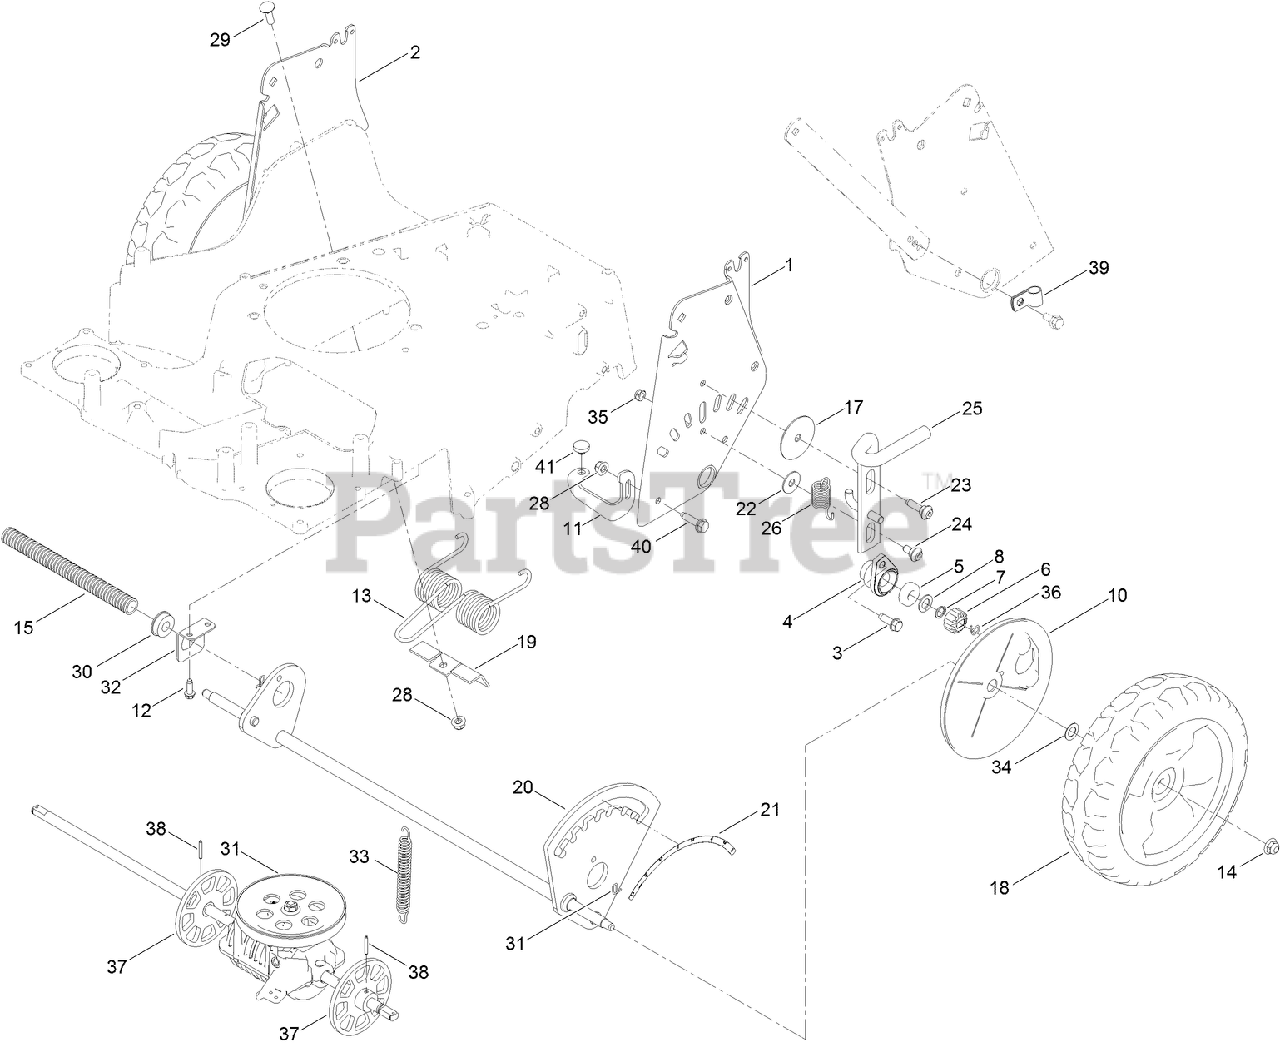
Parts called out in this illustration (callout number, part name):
1	LH HOC PLATE ASM
2	RH HOC PLATE ASM
3	SCREW-THD ROLL, HWH
4	RETAINER-BEARING
5	BEARING-BALL
6	GEAR-PINION, 15T
7	RING-RETAINING
8	WASHER-THRUST
10	COVER-GEAR
11	BRACKET-STOP, ADJUSTABLE
12	SCREW-HWHTF
13	SPRING-TORSION
14	NUT-HF, NI
15	CONDUIT-CONVOLUTED
17	WASHER-PLAIN
18	10.5 INCH WHEEL ASM
19	BRACKET
20	AXLE-REAR
21	DECAL-HOC, REAR
22	WASHER
23	SCREW-SHOULDER, BHTF
24	BOLT-SHOULDER
25	LOCK-HEIGHT, ADJUST
26	SPRING-EXTENSION
28	NUT-HF, NI
29	BOLT-CARR
30	BEARING-BALL
31	TRANSMISSION
33	SPRING-EXTENSION
34	WASHER-PLAIN
35	NUT-LOCK, NI
36	PIN-SNAP
37	ROTOR ASM
38	PIN-ROLL
39	R-CLAMP
40	SCREW-HWHTF
41	BUMPER
